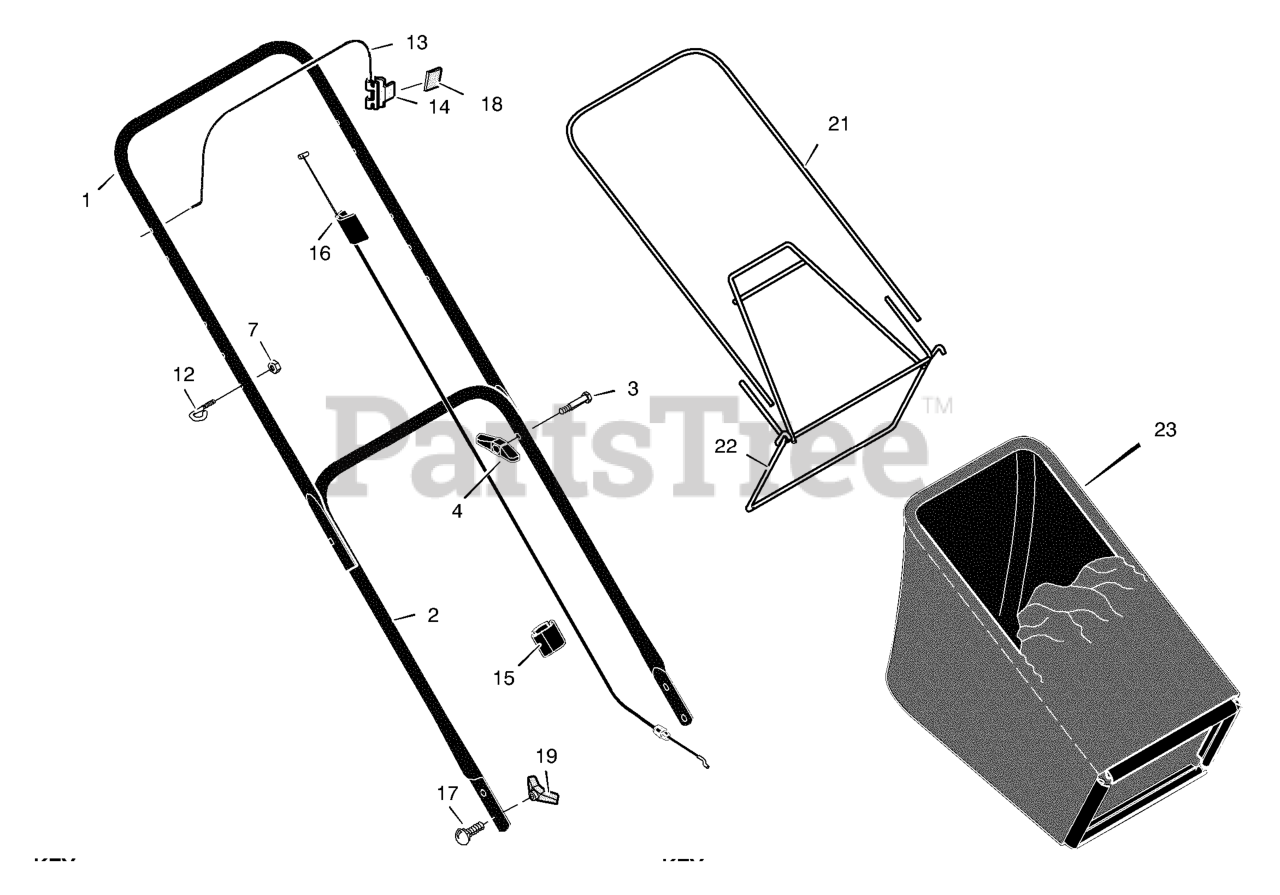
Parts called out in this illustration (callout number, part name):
1	Handle, Upper (Black)
2	Handle, Lower (Black)
4	Knob, Plastic
7	Locknut
12	Guide, Rope
13	Lever, Engine Stop
14	Bracket, Stop Lever
15	Clip, Cable
16	Engine Stop Cable
17	Bolt, Carriage
19	Knob, Plastic
21	Tube, Bag
22	Frame Assembly
23	Bag, Cloth - Black
